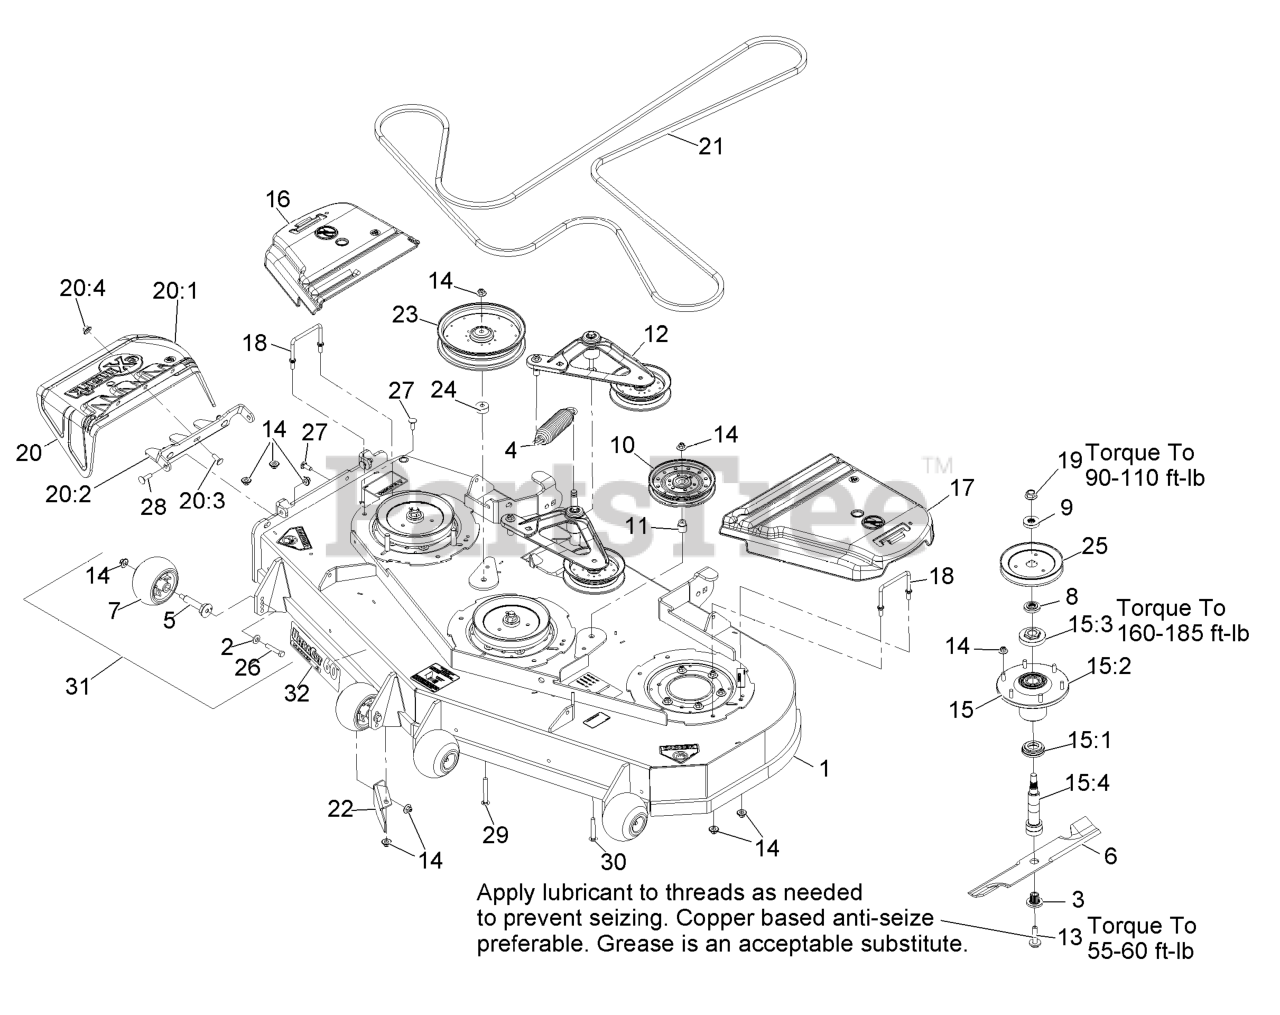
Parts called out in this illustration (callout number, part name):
1	DECK ASM,W/DECALS 60
2	WASHER-BELLEVILLE
3	BUSHING,SPLINED
7	ROLLER-SCALP, ANTI
8	SPACER,SPLINED STEPPED
9	SPACER,SPLINED
11	BUSHING-IDLER
12	DECK IDLER ASM
13	SCREW,SEMS 1/2-20 X 2.19
14	Nut-Nyloc 3/8-16 Flg
15	ASM,SPINDLE HOUSING
15:1	GUARD,BOTTOM
15:2	ASM,CUTTER HOUSING
15:3	NUT, SPINDLE 7/8-14
15:4	SPINDLE,DOUBLE SPLINE
16	COVER-BELT, RH
17	COVER-BELT, LH
18	WIREFORM-COVER
19	NUT-FLANGE, CENTERLOCK
20	ASM,DISCHARGE CHUTE
20:1	CHUTE,DISCHARGE
20:2	BRACKET,DISCHARGE CHUTE
20:3	SCREW-CARR
20:4	Nut-Nyloc 3/8-16 Flg
21	BELT,V-5V-198.75
22	BAFFLE,DISCHARGE 52/60
23	PULLEY-IDLER
24	SPACER-IDLER
25	SHEAVE,BLADE DRIVE 7.25
26	SCREW-HH
27	SCREW-CARR
28	Bolt-Carriage 3/8-16 X 1 1/4
29	SCREW-CARR
30	SCREW-CARR
32	DECAL,ULTRACUT 60 SERIES
